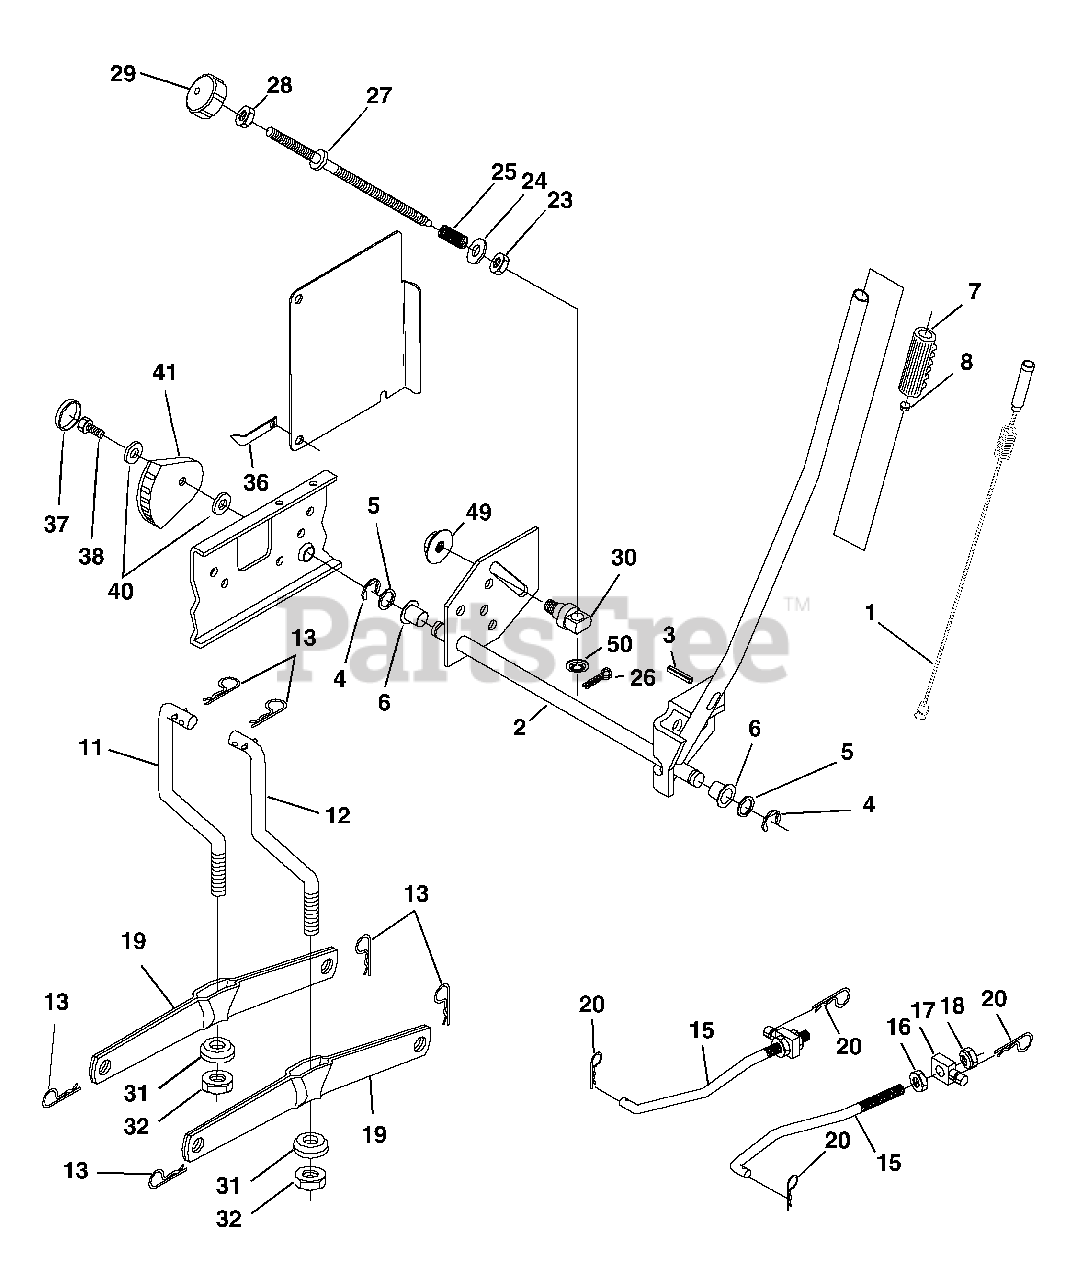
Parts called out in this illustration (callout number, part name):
1	Wire Asm Inner/Sprg W/plunger Lt
2	Shaft Asm Lift RH w/Inf
3	Pin Groove 1 500 Zinc
4	E Ring #5133-62
5	Washer 21/32 X 1 X 21 Ga
6	Bearing Nylon Blk 629 Id
7	Grip Handle Fluted Blk
8	Button Plunger Black
11	Link Lift LH Fixed Length
12	Link Lift RH Fixed Length
13	Retainer Spring
15	Link Front
16	Nut Jam Hex 1/2-13 Unc
17	Trunnion Blk Zinc
18	Nut Lock W/wsh 1/2-13unc
19	Arm Suspension Rear
20	Retainer Spring
23	Nut Special
24	Washer 13/32 X 5/8 X 16 Ga
25	Spring 2-1/8"
26	Pin Cotter 3/32 X 1/2
27	Rod Adj Lift Zinc 7.49 Wrk Lg
28	Nut Hex Jam 3/8-16 Unc
29	Knob Inf 3/8-16 Unc Blk W/sym
30	Trunnion Infin Height
31	Bearing Pvt Lift Spherical
32	Nut Crownlock 3/8 - 24
36	Indicator Height STLT
37	Plug Hole Blk 1.485/1.515 Dia.
38	Screw Thdrol 5/16-18 x 3/4
40	Washer 11/32 x 1-1/2 10 Ga.
41	Scale Ind. Height Blk.
49	Nut Hex Flange Lock
50	Nut Push Phos & Oil
